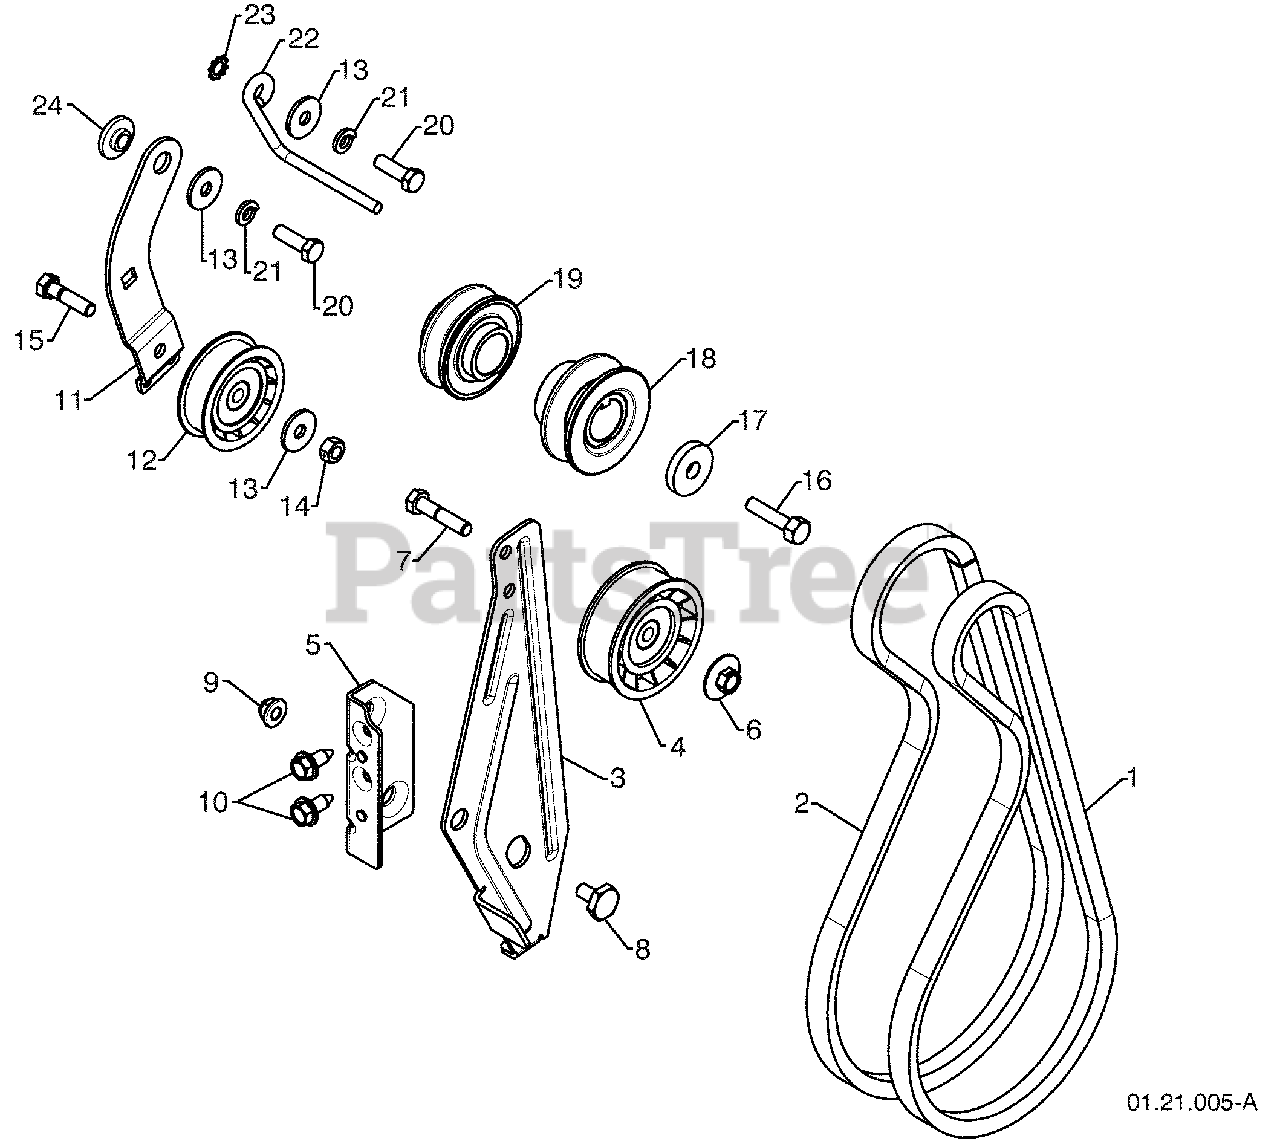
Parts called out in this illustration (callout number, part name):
1	IMPELLER BELT
2	TRACTION BELT
3	IDLER ARM BRACKET
4	IDLER PULLEY
5	IDLER BRACKET
6	NUT 5/16-18
7	SCREW 5/16-18 X 1.50
8	SHOULDER BOLT 5/16-18 X .50
9	NUT 5/16-18 NYLOCK
10	SCREW 5/16-18 X .75
11	TRACTION IDLER BRACKET
12	TRACTION PULLEY
14	NUT 5/16-18
15	SCREW 5/16-18 X 1.25
16	SCREW 3/8-24 X 1.375
18	PULLEY ENG IMPELLER
19	PULLEY ENG TRACTION
20	SCREW 5/16-24 X 1.00
21	LOCKWASHER 5/16
22	BELT GUIDE
23	LOCKWASHER 5/16
24	IDLER BUSHING
